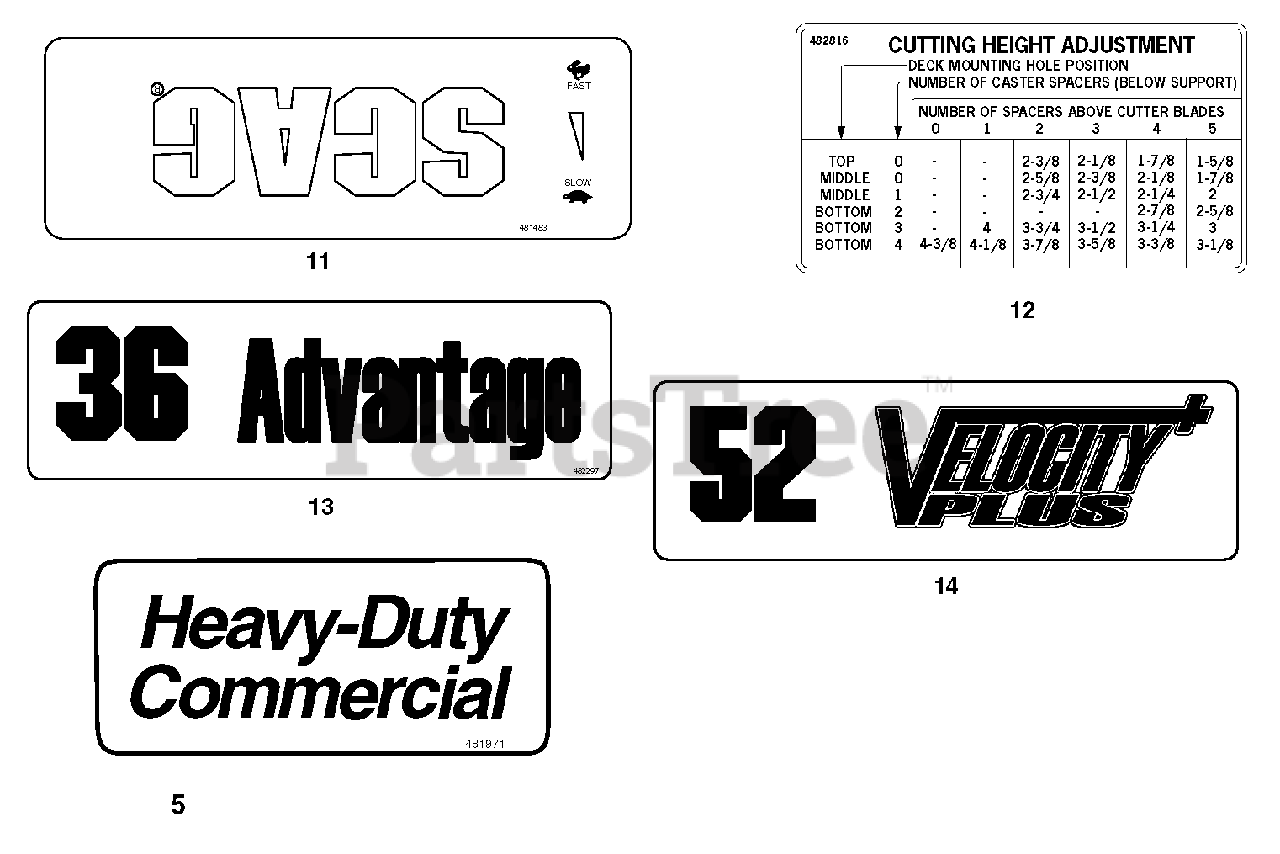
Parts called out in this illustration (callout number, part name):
5	Decal, Heavy Duty Commercial
11	Decal, Instrument Panel - Front
12	Decal, Height of Cut
13	Decal, 32
13	Decal, 36 Advantage
14	Decal, 48 Velocity Plus
14	Decal, 52 Velocity Plus
